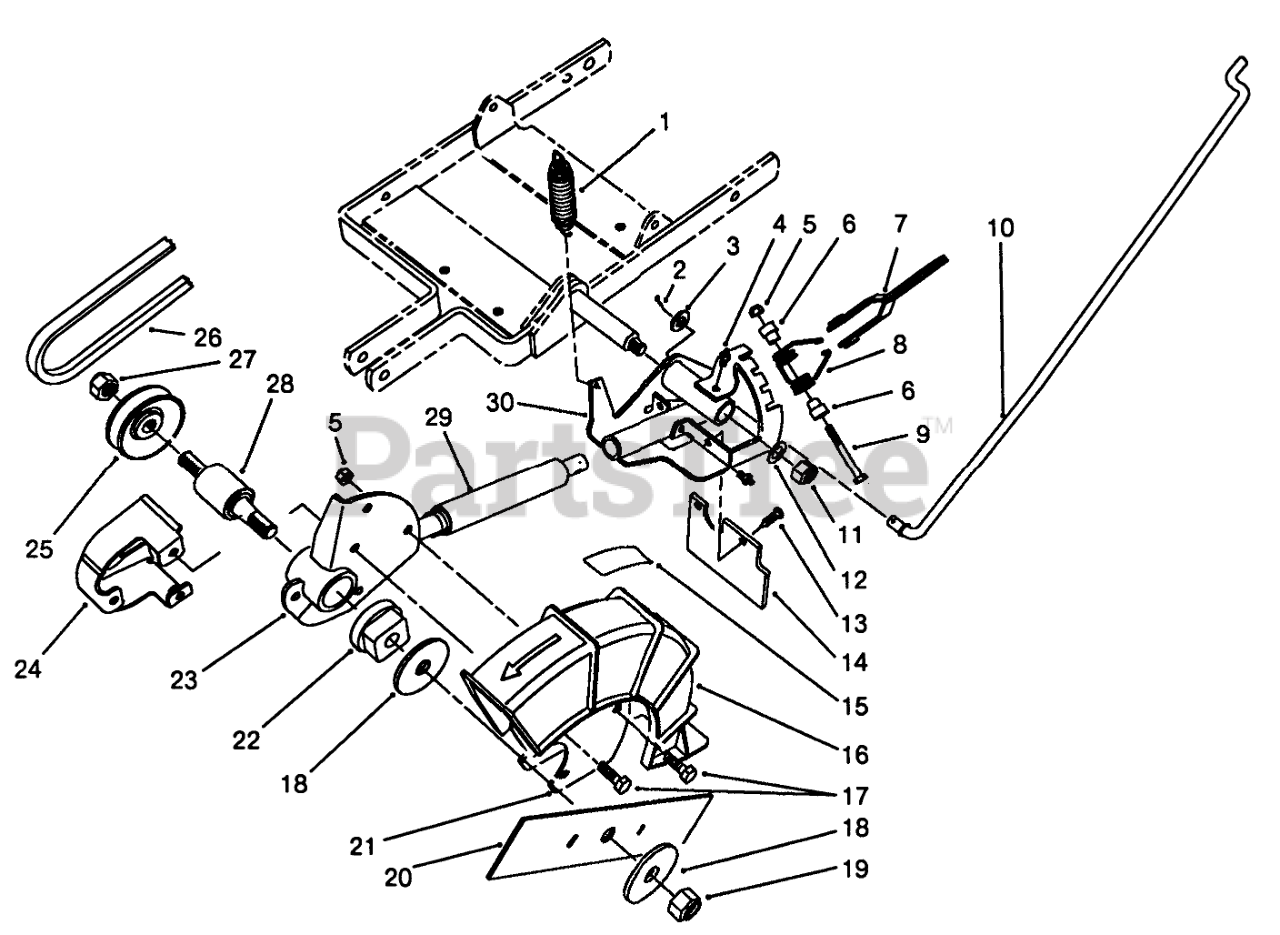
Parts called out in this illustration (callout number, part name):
1	EXT. SPRING
2	PIN-COTTER
3	WASHER-FLAT
4	FITTING-GREASE
5	NUT-LOCK, NI
6	SPACER-PIVOT LEVER
7	LEVER WA
8	TORSION SPRING
9	SCREW-HH
10	LOWER CONTROL ROD
11	NUT-LOCK, NI
12	WASHER-PLAIN
13	PANEL FASTENER
14	RUBBER GUARD
15	DECAL-BLADE
16	Blade Guard Assembly (Incl. Ref. #15)
17	SCREW-HWHTF
18	WASHER-LARGE
19	NUT-HEX
20	10" EDGER BLADE B
21	GUARD PLATE
22	BRG SHIELD
23	HUB ASM
24	PULLEY GUARD WA
25	PULLEY
26	V-BELT
27	NUT-LOCK, NI
28	SPINDLE ASM
29	SPRING & BELLOW ASM
30	PIVOT ARM WELDMENT B
